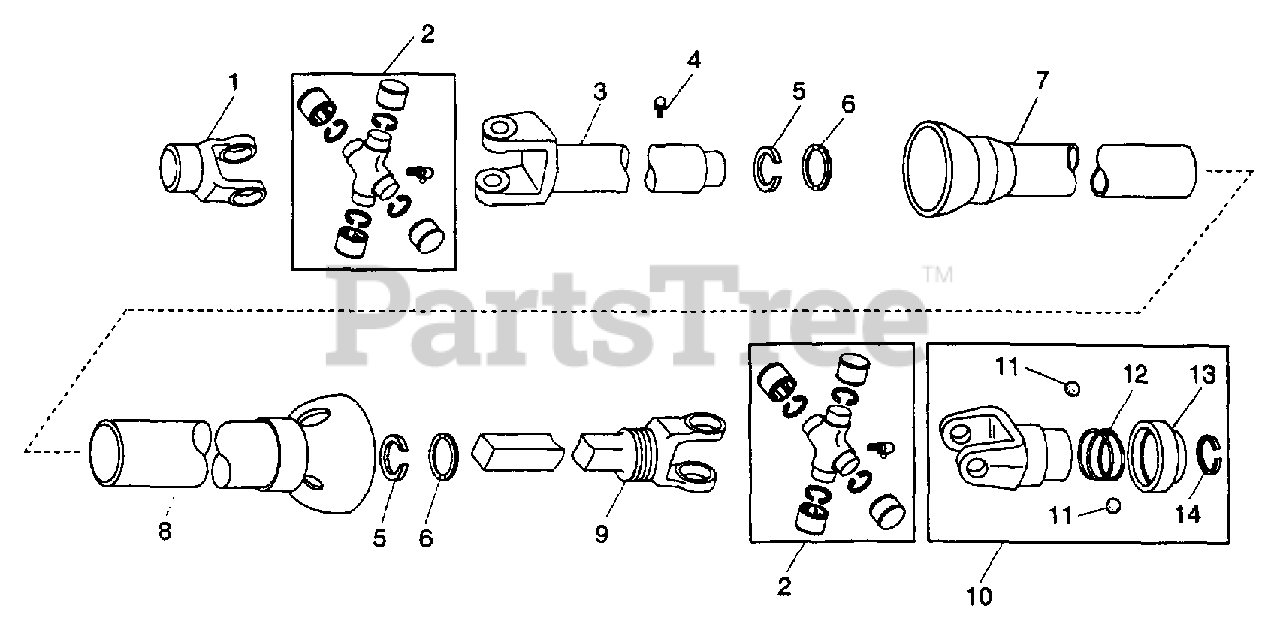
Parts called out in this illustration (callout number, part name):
1	END YOKE
2	REPAIR KIT
3	YOKE AND TUBE
4	ZERK FITTING
5	RG-RTNG WEASLER #2A N20
6	BRG-BALL NYL WEASLER
7	MALE GUARD TUBE
8	FEMALE GUARD TUBE W/DECAL
9	YOKE AND SHAFT
10	LOCK YOKE ASSEMBLY
11	STAINLESS BALL
12	SG ??X??X?? WEASLER
14	RG-RTNG
